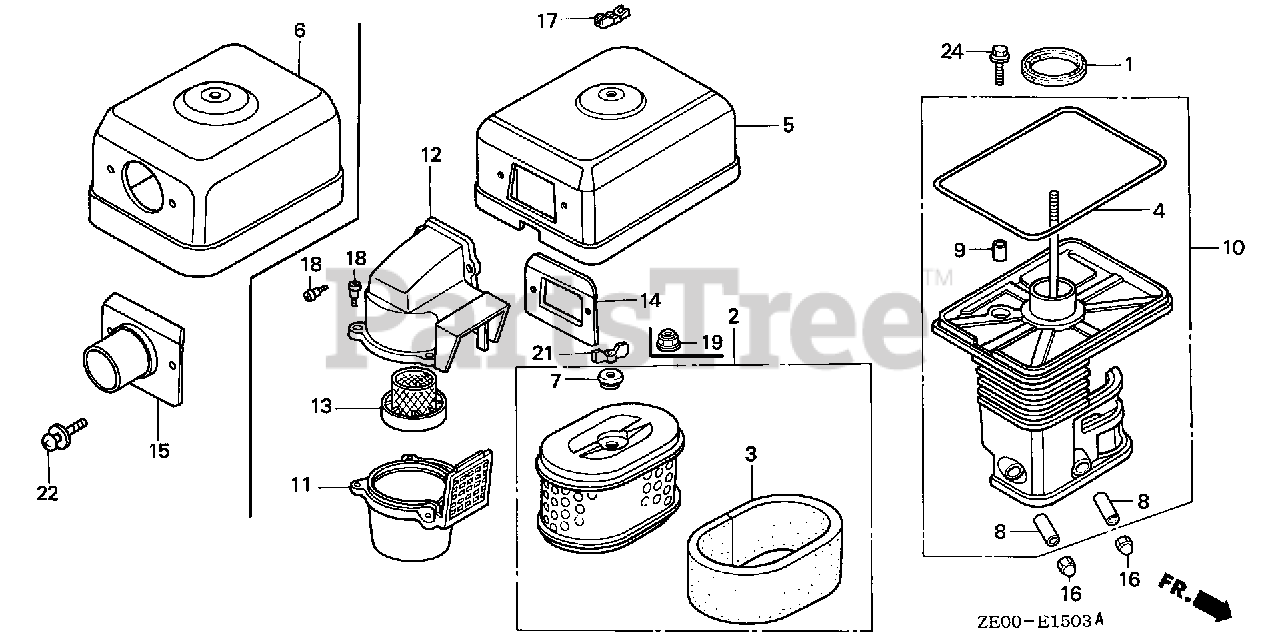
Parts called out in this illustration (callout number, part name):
1	GASKET, ELBOW
2	ELEMENT, AIR CLEANER (DUAL)
3	FILTER (OUTER)
4	GASKET, AIR CLEANER COVER
5	COVER, AIR CLEANER (CYCLONE)
7	GROMMET, AIR CLEANER
8	COLLAR, AIR CLEANER
9	COLLAR B, AIR CLEANER
10	ELBOW, AIR CLEANER
11	CASE, PRE AIR CLEANER
12	CAP, PRE AIR CLEANER
13	GUIDE, PRE AIR CLEANER
14	PLATE, PRE AIR CLEANER
16	NUT, CAP (6MM)
17	NUT, AIR CLEANER COVER (DACRO COATING)
18	BOLT, SPLASH GUARD
21	NUT, TOOL BOX SETTING
24	BOLT, FLANGE (6X20)
